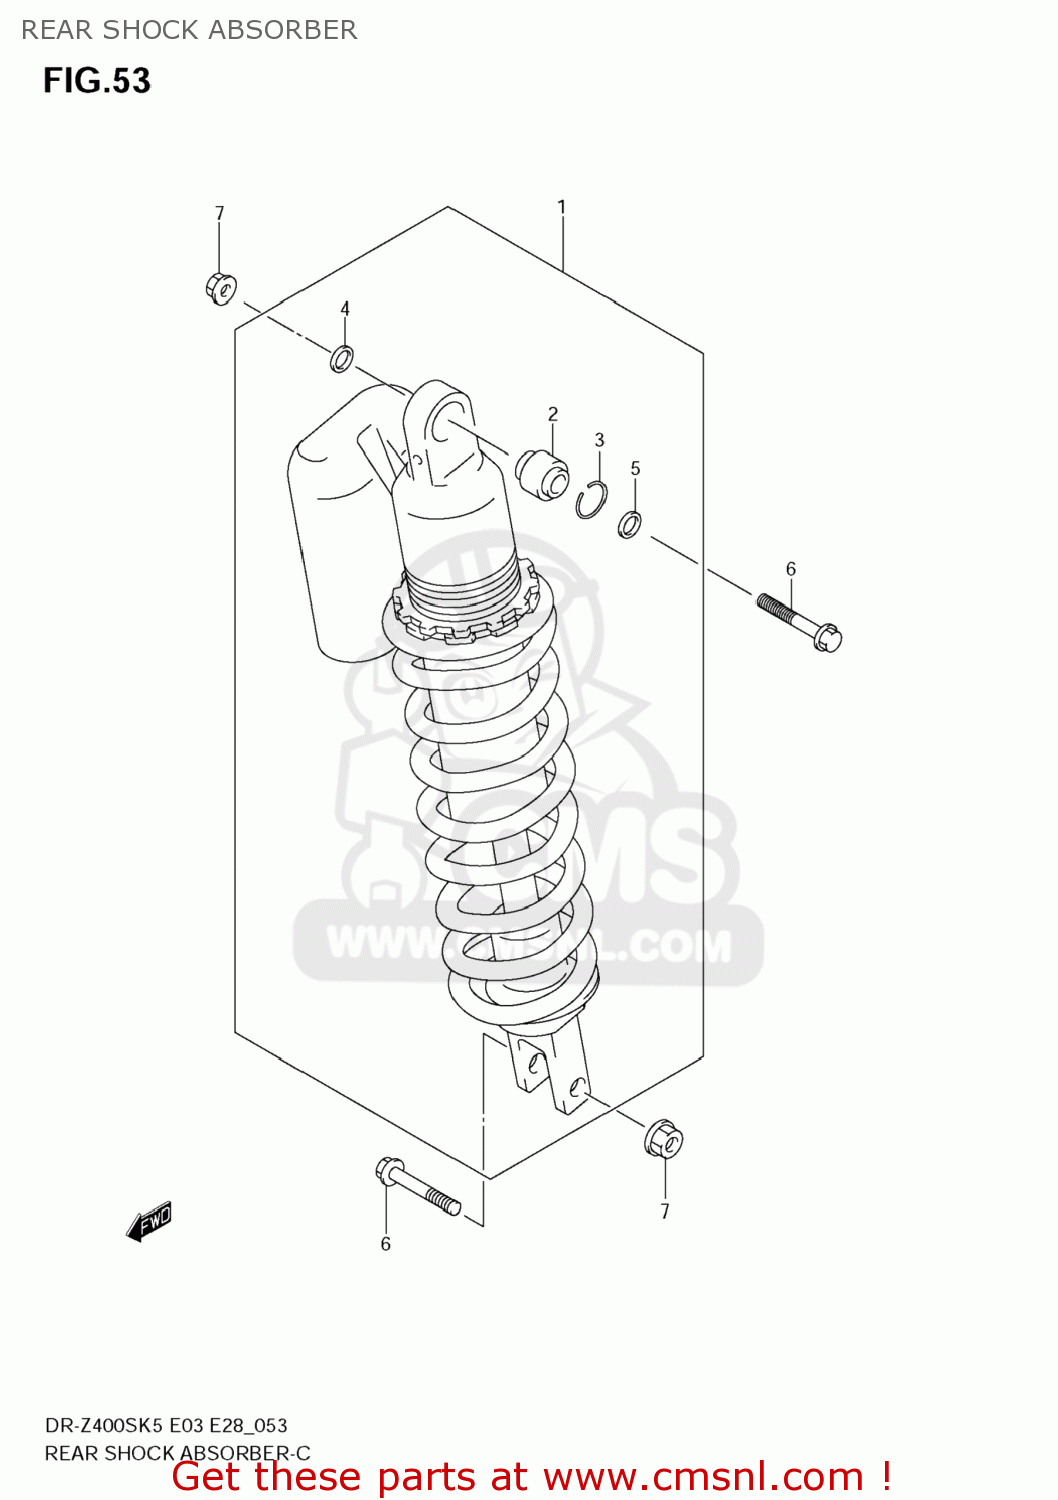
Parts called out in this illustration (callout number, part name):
1	ABSORBER ASSY,RR SHOCK(WHITE)
2	BEARING,RR SHOCK ABSORBER
3	RING,STOPPER
4	SEAL,DUST UPR,R
5	SEAL,DUST UPR,L
6	BOLT(10X47.5)
7	NUT
